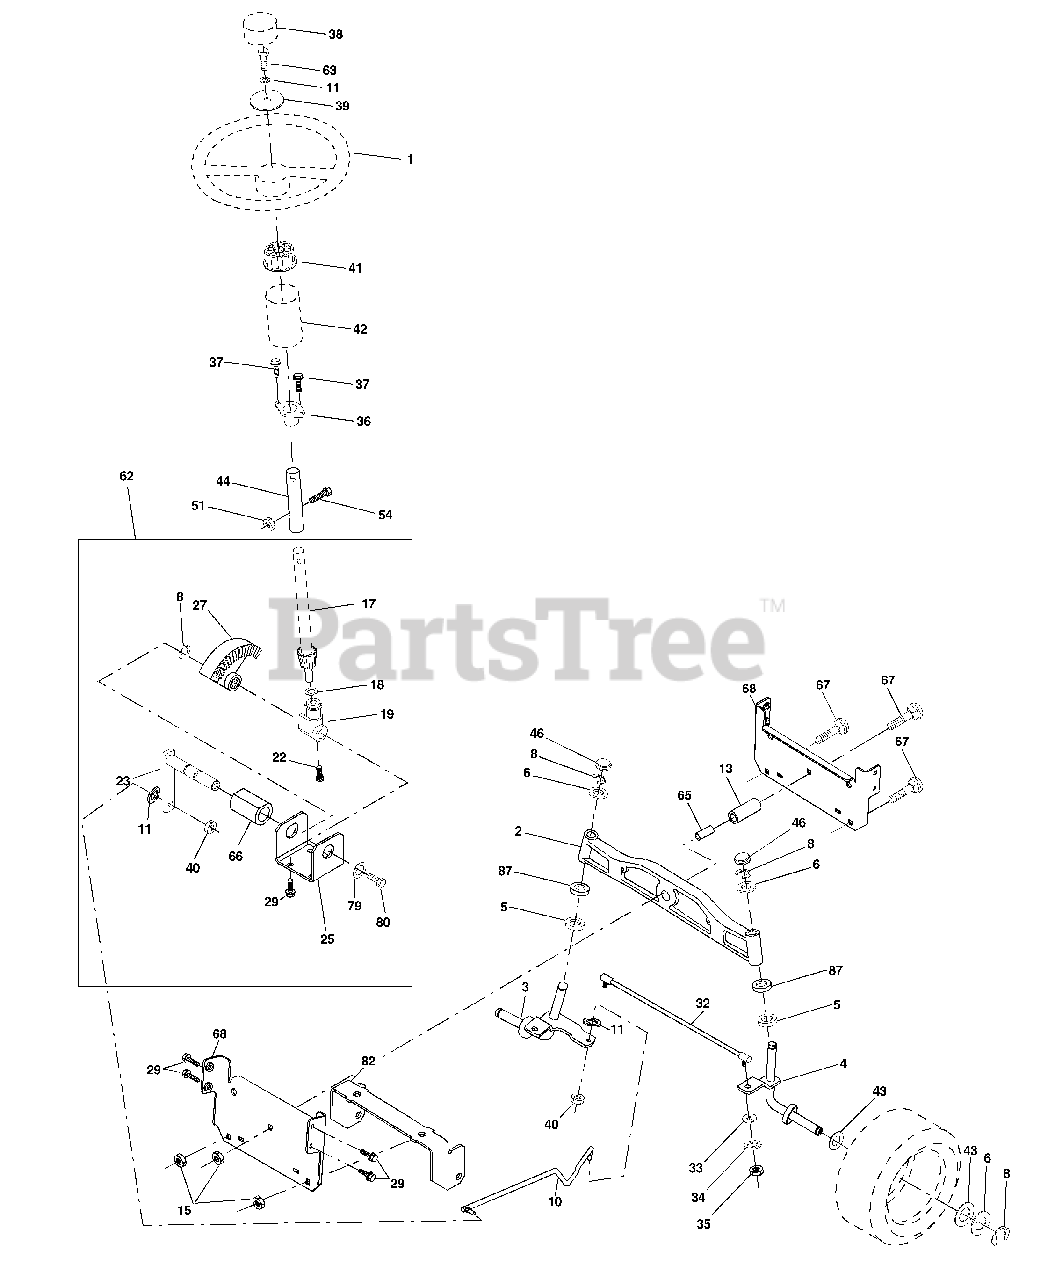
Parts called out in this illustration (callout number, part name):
1	Wheel Steering
2	Axle Cast LT Machined
3	Spindle Asm Cast LH
4	Spindle Asm Cast RH
5	Bearing Race Thrust Harden
6	Washer 25/32 X 1-5/8 X 16 Ga
8	Ring Klip #t5304-75
11	Washer Lock Hvy Hlcl Spr 3/8
13	Spacer Brg Axle Front
15	Nut Hex Flange Lock Yel D
17	Shaft Asm Strg Private Label
18	Washer Thrust 515x 750x 033
19	Support Shaft
22	Screw Hex Wshhd Torx
23	Shaft Asm Pittman
25	Bracket Steering
27	Gear Sector 22 Teeth
29	Screw 3/8-16x3/4
33	Washer 11/32 x 3/4 x 16 Ga.
34	Washer Lock Hvy. Helical 5/16 SD
35	Nut Crown Lock 5/16-24
36	Bushing Strg
37	Screw TT #32.5 x 5 x 3/8 Flange
38	Cap Wheel Steer
39	Washer 13/32 x 1-1/20 x 11 Ga.
40	Nut Lock Center 3/8-24 Unf
41	Adaptor Wheel Strg
42	Boot Dash Steering
43	Washer 25/32 X 1 1/4 X 16 Ga
44	Extension Steering Non-adjust
46	Cap Spindle Fr Top Blk
51	Nut Lock Hex W/Ins 5/16-18 UNC
54	Bolt Fin Hex 5/16-18 UNC x 1-1/4
62	Steering Assembly
63	Bolt Fin Hex 3/8-16 UNC x 1 Gr. 5
65	Spacer, Brace Axle
66	Bearing Arm Pittman
67	Bolt Rdhd 3/8-16 x 2-1/4
68	Brace, Axle
79	Washer 13/32 x 1-1/4 x 12 Ga.
80	Bolt Hex Nylon 3/8-16 x 3/4
82	Bracket Susp Chassis Front 15"
87	Washer Flat .781 x 1-1/2 x .14
